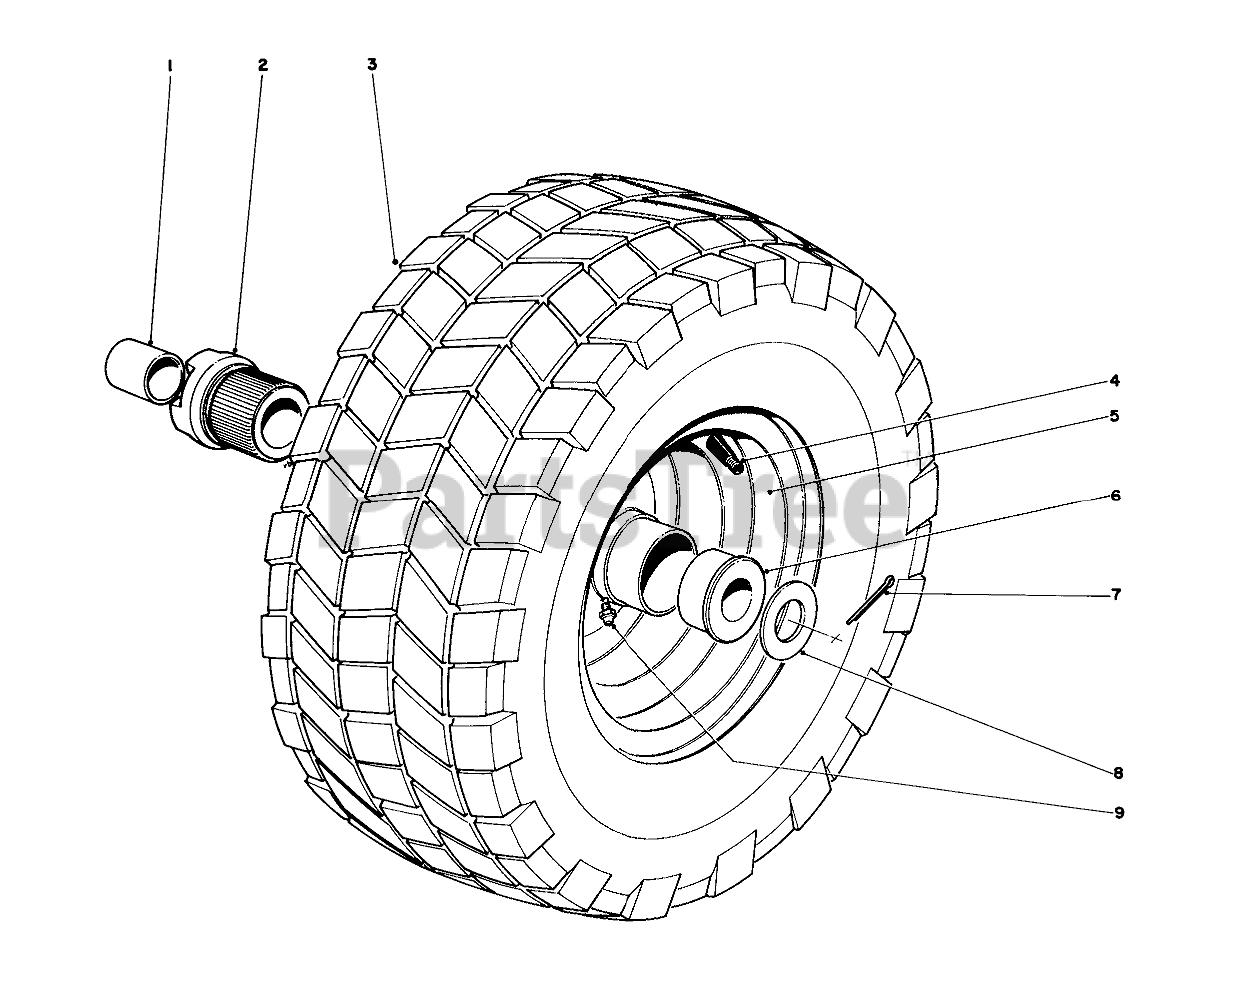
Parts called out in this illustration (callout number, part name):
1	.877ID X .750LG BSHG
2	JAW HUB
3	Tire
4	STEM-VALVE
5	Wheel Rim
6	Bushing
7	PIN-COTTER
8	WASHER-THRUST
9	FITTING-GREASE
